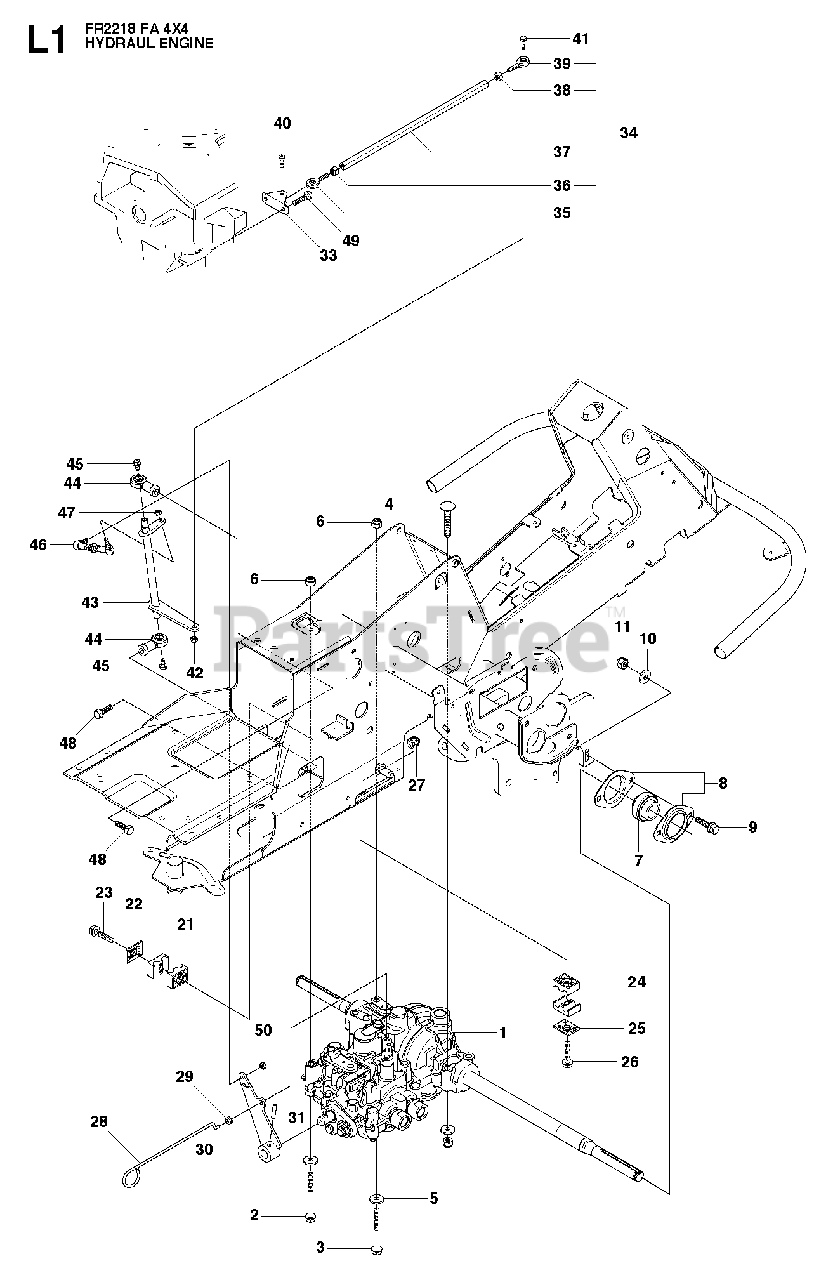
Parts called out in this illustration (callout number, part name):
1	TRANSMISSION
5	WASHER BRB 8.4X17
6	LOCKNUT M8
8	BEARING HOUSING
9	BOLT
10	WASHER BRB 8.4X17
11	LOCKNUT M8
21	PIPE CLAMP
24	PIPE CLAMP
25	COVER PLATE
26	SCREW EHHFM
29	FUEL TANK BUSHING
35	LINK
36	NUT
37	ROD
38	NUT
39	LINK
42	NUT FLANGE - M6
45	SCREW EHHFM
46	ADJUSTING ROD
47	NUT FLANGE - M6
48	SCREW M10X25
50	LOCKNUT M6
